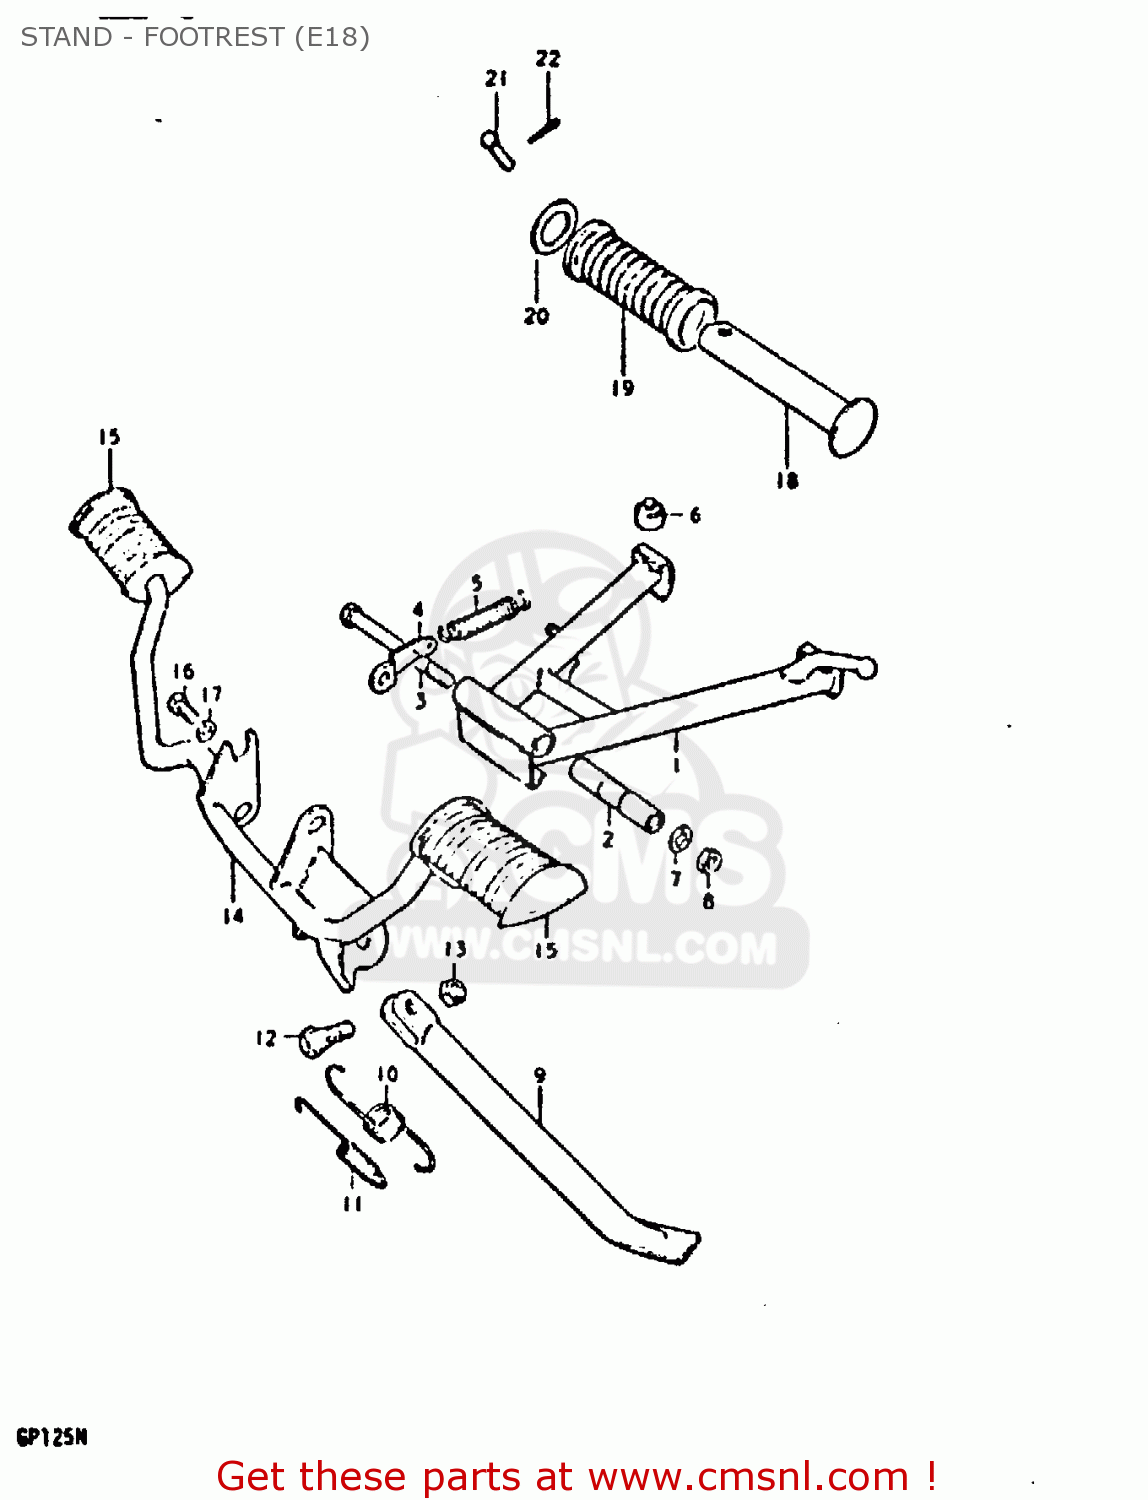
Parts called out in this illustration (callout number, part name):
1	STAND,CENTER
2	SPACER
3	BOLT(10X110)
4	HOOK,CTR STAND SPRING
5	SPRING
6	CUSHION
7	LOCK WASHER
8	NUT
9	STAND, PROP
10	SPRING, OUTER
11	SPRING
12	BOLT(10X28)
13	NUT
14	BAR, FRONT FOOTREST
15	RUBBER,FR FOOTREST
16	BOLT
17	LOCK WASHER
18	BAR,FOOTREST RUBBER
19	RUBBER,PILLION FOOTREST
20	WASHER (19.5X32X2)
21	PIN
22	PIN 20X20
